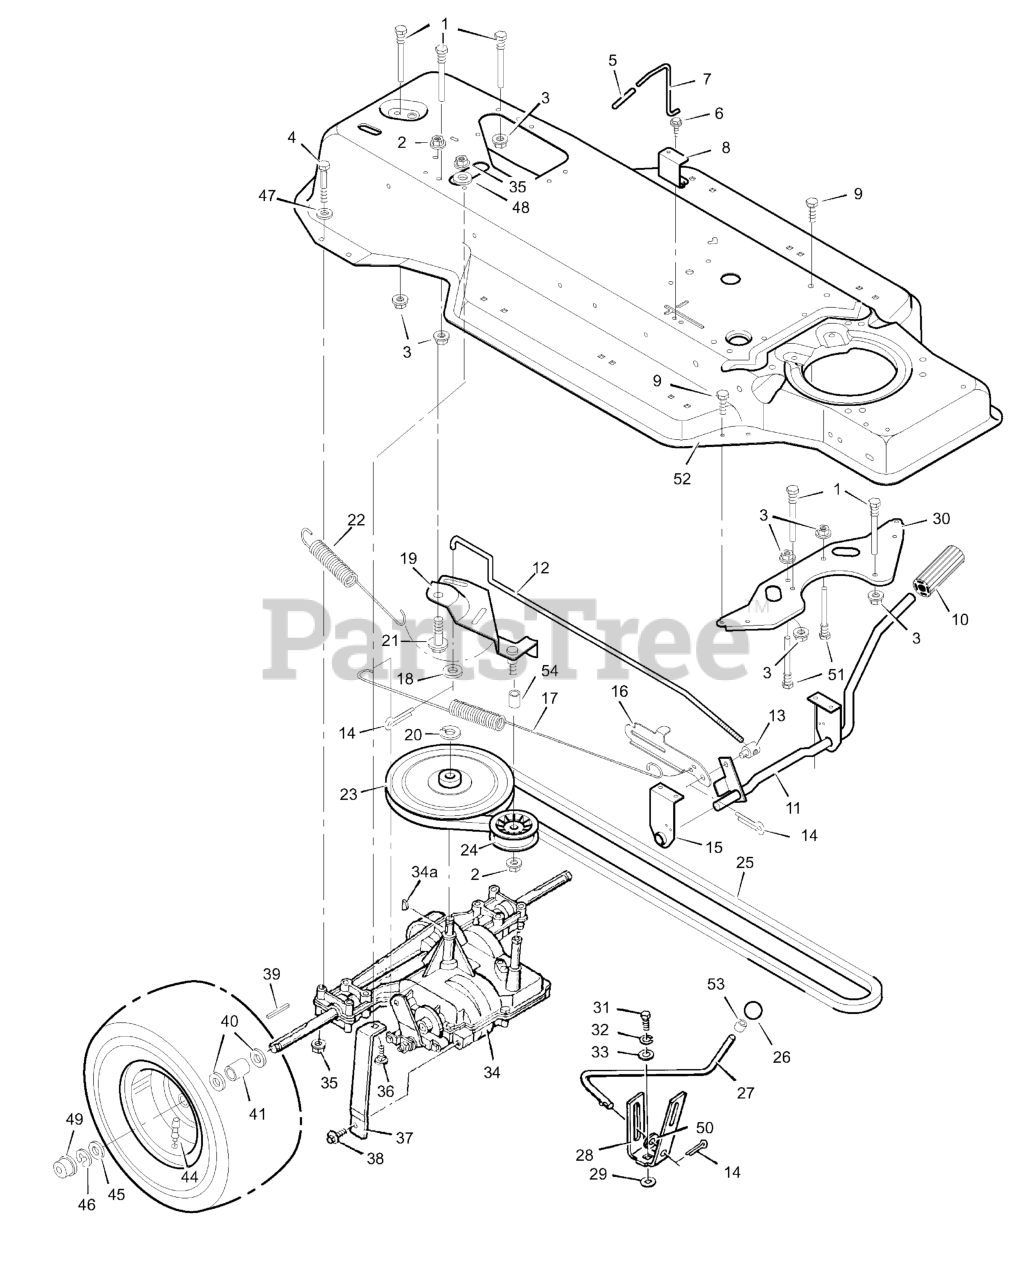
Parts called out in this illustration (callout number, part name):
1	Guide, Belt
2	Locknut, Flange
3	Nut, Flange
4	Bolt, Hex
7	Rod, Control
8	Guide, Bracket
10	Clutch and Brake Pedal
11	Lever Assembly
12	Rod, Clutch
13	Nut, Adjustable
14	Pin, Cotter
15	Bracket, Support
16	Latch, Park Brake
17	Spring, Brake Extension
18	Washer
19	Bracket Assembly, Idler
20	Ring, Retainer
21	Bolt, Shoulder
22	Spring, Drive Extension
23	Pulley, Motion Drive
24	Pulley, Backside Idler
25	Belt, Motion Drive
26	Knob, Shift Lever
27	Lever, Shift
28	Yoke, Shift
30	Plate, Belt Guide
31	Bolt, Hex
32	Lockwasher
34	Transaxle, Peerless **
34A	Woodruff Key No. 9
35	Nut, Flange
36	Bolt, Carriage
37	Support, Transaxle
39	Key, Square
41	Spacer, Transaxle
43	Wheel & Tire Assembly
44	Stem, Valve
47	Washer
49	Hub Cap
50	Washer
51	Guide, Belt
52	Frame Assembly
53	Ring, Tolerance
